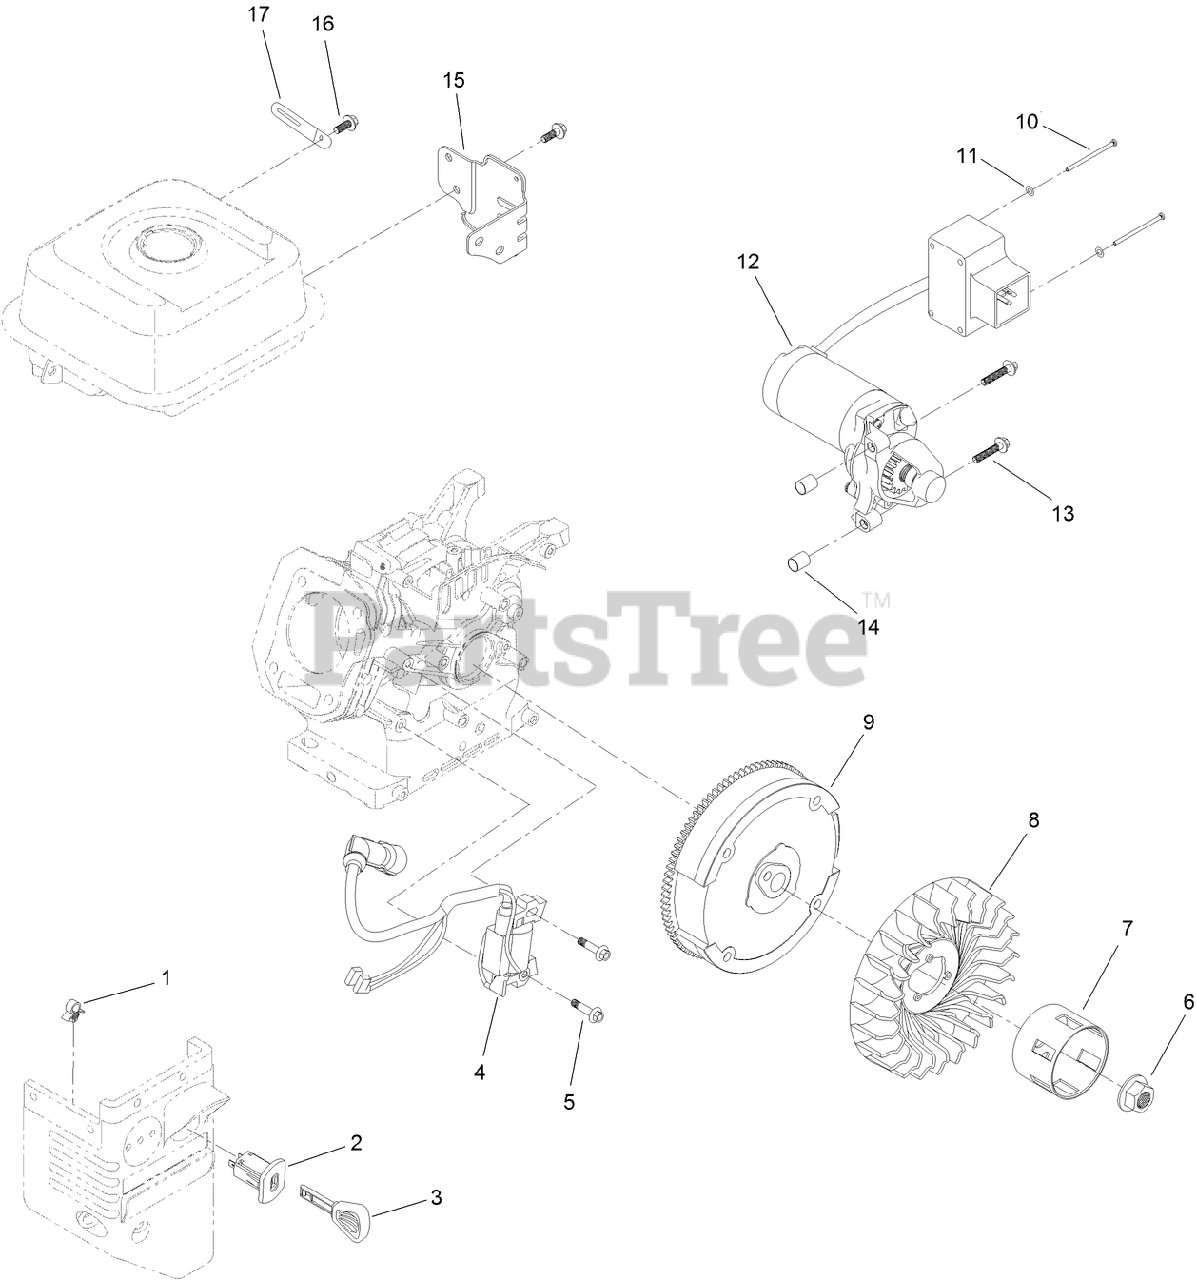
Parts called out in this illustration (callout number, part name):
2	SWITCH-KEY
5	SCREW-HHF
6	NUT-FLANGE
7	CUP-STARTER
9	FLYWHEEL
10	SCREW-BHP
11	WASHER-PLAIN
12	MOTOR-STARTER
13	SCREW-FLANGE
14	PIN-DOWEL
15	BRACKET-BOX, SWITCH
16	SCREW-HHF
17	CLIP-HARNESS, WIRE
